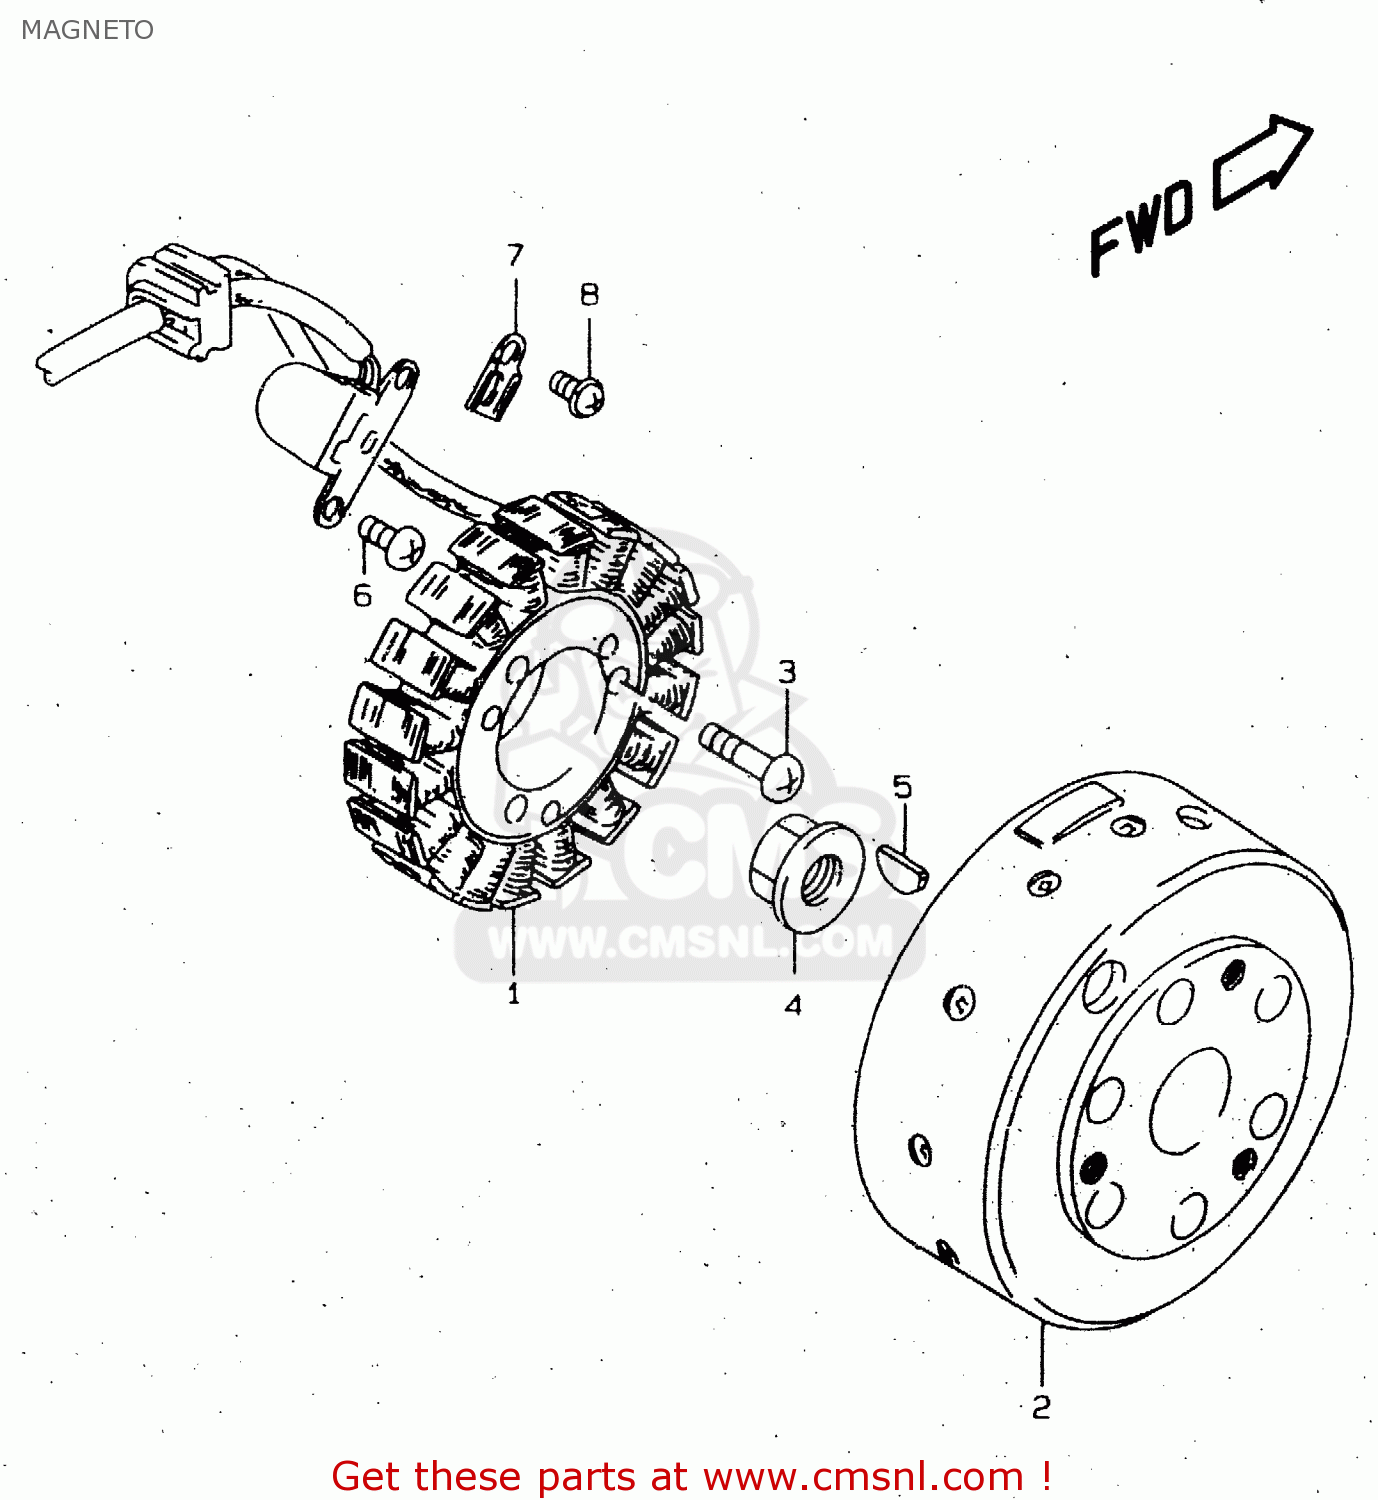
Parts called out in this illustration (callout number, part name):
1	STARTER ASSY
2	ROTOR
3	SCREW
4	NUT,GENERATOR ROTOR
5	KEY
6	SCREW
7	CLAMP,GENERATOR LEAD WIRE
8	SCREW
